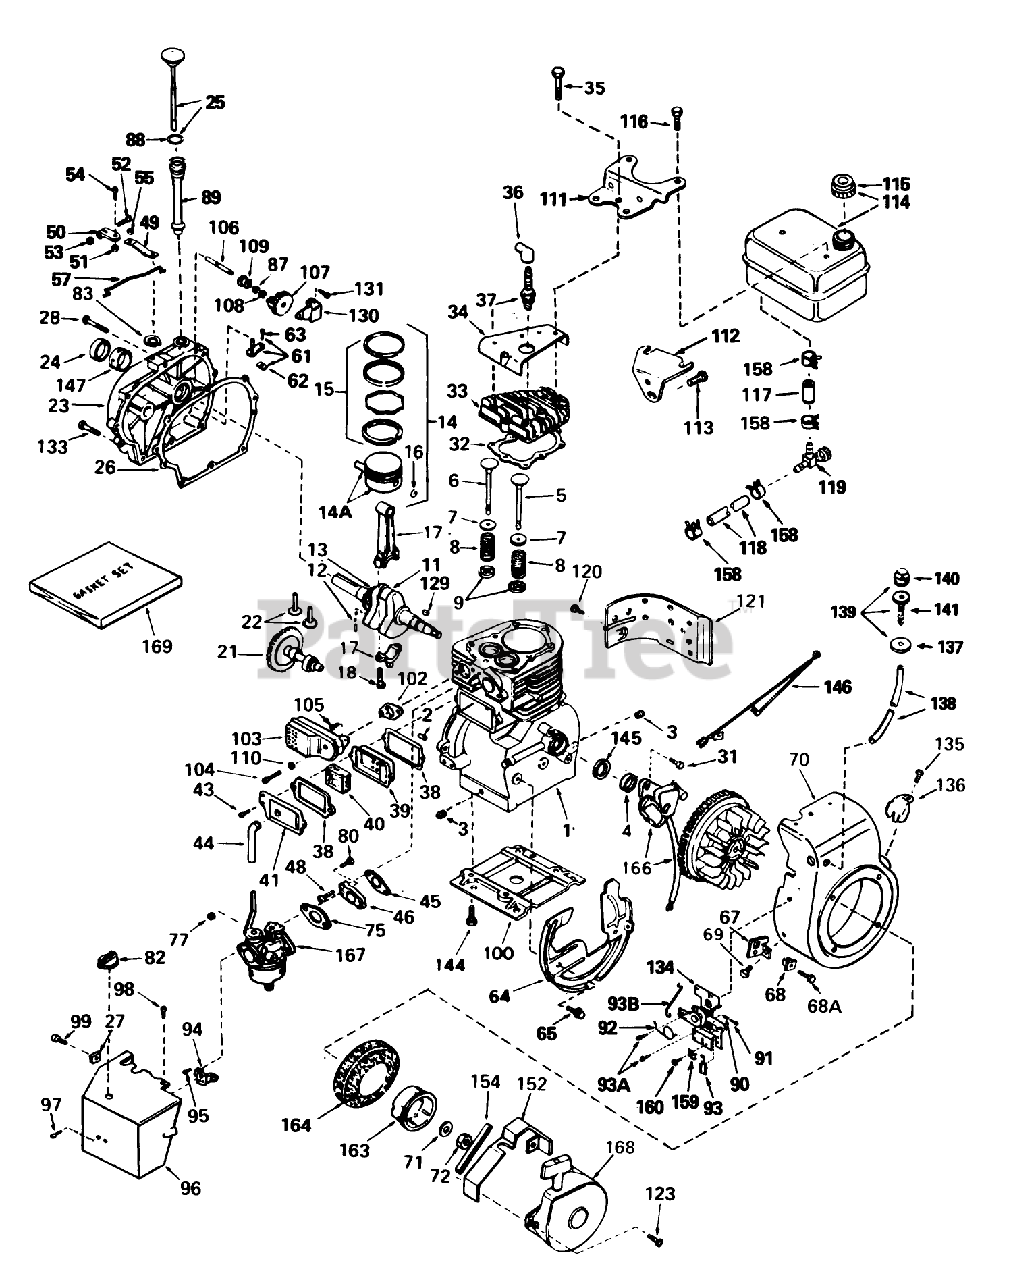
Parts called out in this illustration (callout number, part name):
1	Cylinder Assy. (Incl. Ref. #2, 3, 4 5)
2	Pin-Dowel
3	Plug-Drain, Oil (SQH 1/4-18)
4	Seal, Oil
5	Valve, Intake (Standard)(Incl. No. 9)
5	Valve, Intake (1/32" oversize)(Incl. No. 9)
6	Valve, Exhaust (Standard)(Incl. No. 9)
6	Valve, Exhaust (1/32" oversize)(Incl. No. 9)
7	Cap-Spring, Valve
8	Spring-Valve
9	Keeper-Spring, Valve
11	Crankshaft Assy. (Incl. Nos. 12 13)
12	Pin, Groove
13	Gear-Crankshaft
14	Piston, Pin Ring Assy. (Std.)(Incl. Ref. #14A, 15 16)
14	Piston, Pin Ring Assy. (.010 Oversize)(Incl. Ref. #14A, 15 16)
14	Piston, Pin Ring Assy. (.020 Oversize)(Incl. Ref. #14A,15 16)
14A	Piston Pin Assy. (Std.)(Incl. Ref. #16)
14A	Piston Pin Assy. (.010 Oversize)(Incl. Ref. #16)
14A	Piston Pin Assy. (.020 Oversize)(Incl. Ref. #16)
15	Ring Set, Piston (Std.)
15	Ring Set, Piston (.010 Oversize)
15	Ring Set, Piston (.020 oversize)
17	Rod Assy., Connecting (Incl. Ref. #18)
18	Bolt, Connecting Rod
21	Camshaft, BCR
22	Lifter-Valve
23	Cover, Cylinder (Incl. Nos. 24 106)
24	Oil Seal
25	Dipstick, Oil (Incl. Ref. #88)
26	Gasket-Cover, Cylinder
27	Nut-U Type
28	Screw (1/4-20 x 1-1/4)
31	Screw
32	Gasket-Head, Cylinder
33	CYLINDER HEAD
34	Cover-Head, Cylinder
35	Screw (5/16-18 X 2-1/2)
36	Cover-Spark Plug
37	Plug, Spark (J17LM or equiv.)
37	Plug, Spark (Champion RCJ-8)
38	Gasket-Breather
39	Body-Breather
40	Element-Breather
41	Cover-Valve
43	Screw
44	Tube-Breather
45	Gasket-Intake
46	Flange, Carburetor (Incl. Nos. 77 80)
48	Screw
49	Lever-Governor
50	Clamp-Lever, Governor
51	Nut-Lock
52	Screw
53	Nut-Lock
54	Screw
55	Washer-Lock
57	Governor Link
61	Rod, Governor (Incl. Nos.62 63)
62	Yoke-Governor
63	Screw (6-40x5/16)
64	Baffle Blower Housing
65	Screw (1/4-20x19/32)
67	Bracket
68	Grommet
68A	Screw
69	Screw, Hex Hd.
70	Housing, Blower (Incl. Ref. #135 136)
71	Washer
75	Gasket-Carburetor
77	Nut and Lock Washer (1/4-28)
80	Screw
82	Knob-Control
83	Ring-Retaining
87	Washer-Flat
88	O-Ring
89	Tube Fill
90	Spring-Compression
91	Screw
92	Spring-Throttle
93	Terminal
93A	Screw (10-32 x 1/2)
93B	Link-Throttle
94	Bracket-Choke
95	Screw (10-32 x 1/2)
96	Cover, Carburetor
97	Screw (8-32 X 5/16)
98	Screw (10-32x1/2)
99	Screw (8-32 x 3/8)
100	Base Engine
102	Gasket Exhaust
103	Muffler
104	Screw (5/16-18 X 2)
105	Screw
106	Shaft-Governor
107	Governor Gear ASM
108	Ring-Retaining
109	Spool, Governor
110	Washer
111	Plate, Fuel Tank Mounting
112	Bracket, Fuel Tank-Lower
113	Screw (1/4-20x19/32)
114	53023/VAR.10/16HP O
115	Cap, Fuel
116	Screw (1/4-15x7/8)
117	Line-Fuel
118	Line-Fuel (8.62)
119	Valve-Shut Off
120	Screw
121	Emnsion, Blower Housing
123	Screw
129	Key, Flywheel
130	Bracket, Governor
131	Screw (10-32 x 35/64)
133	Screw
134	Control Assy., Remote Speed (Incl. Ref. #90 thru 93)
135	Screw (8-32 x 3/8)
136	Screw
137	Retainer, Primer Bulb
138	Line, Primer
139	Primer Assy. (Incl. Nos. 89, 90 91)
140	Bulb, Primer
141	Body, Primer
144	Screw
145	Gasket Stator
146	Wire, Ground
147	Bushing-Crankshaft
152	Guard-Starter
154	Seal, Snowguard
158	Clamp-Line, Fuel
159	Conduit
160	Screw (10-32 x 3/8)
163	Cup-Starter
164	Screen, Air
166	Magneto
167	Carburetor (Incl. Ref. #75)
168	Starter Assy., Rewind
169	Gasket Set (Incl. Items Marked *)
